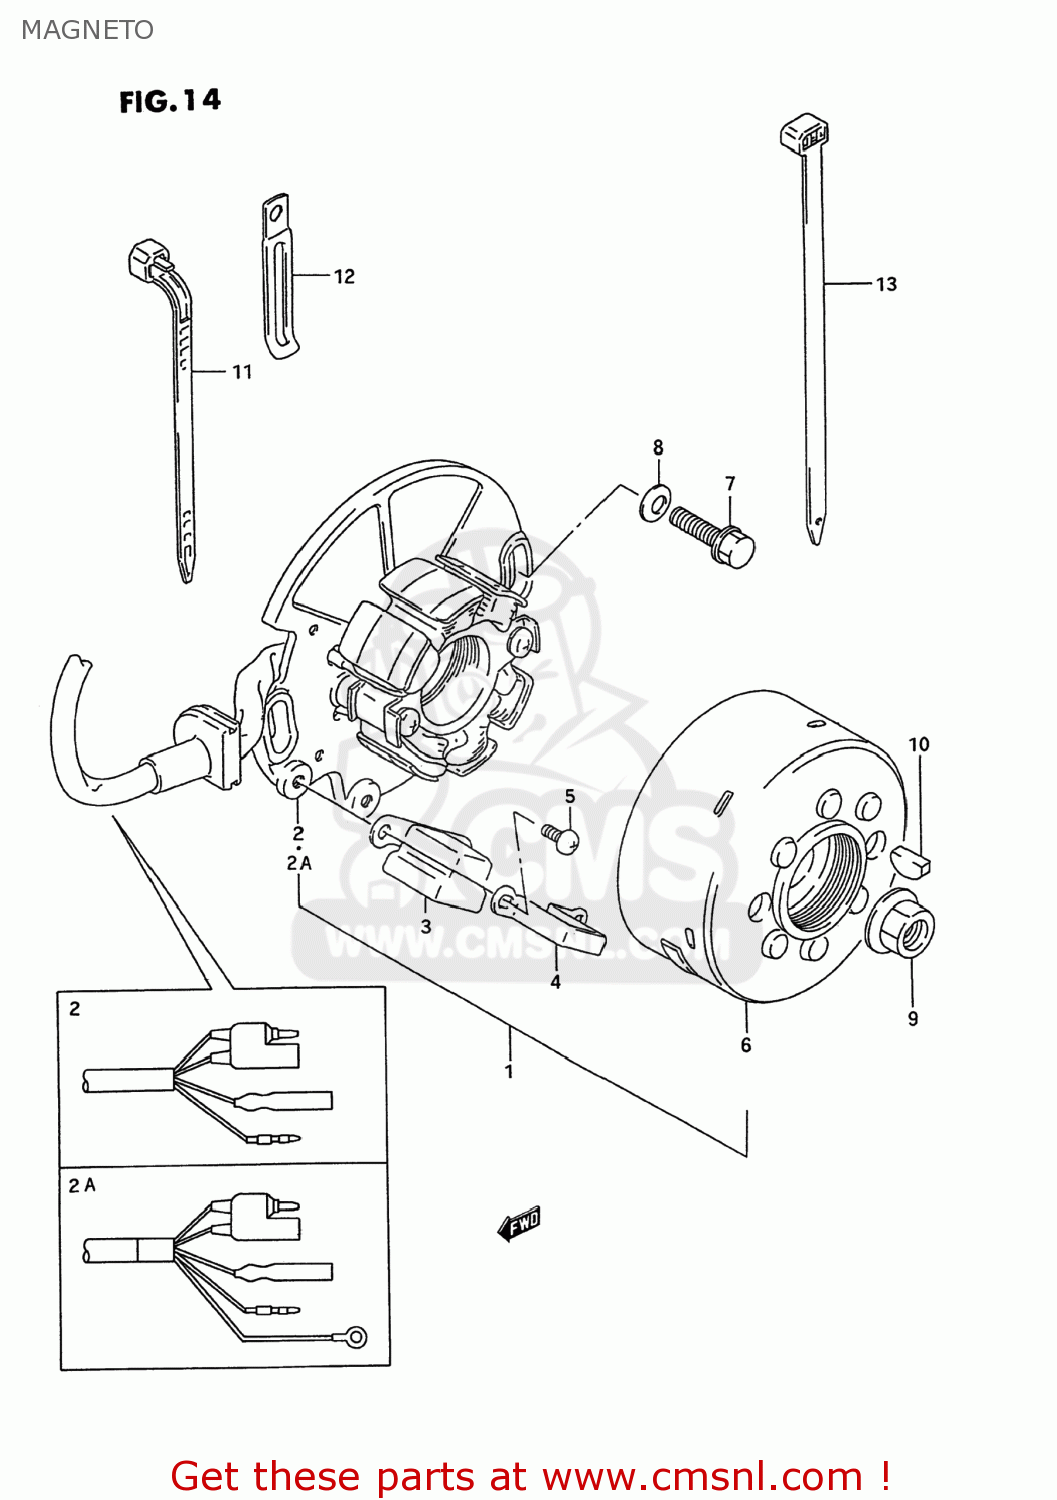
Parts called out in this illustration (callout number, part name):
1	MAGNETO ASSEMBLY
2	STARTER ASSY
2A	STARTER ASSY
2B	STARTER ASSY
3	COIL ASSEMBLY,PICK-UP
4	HOLDER,PICK UP COIL
5	SCREW
6	ROTOR
7	BOLT
8	WASHER
9	NUT
10	KEY
11	CLAMP(L:125)
12	CLAMP
13	CLAMP L:165
